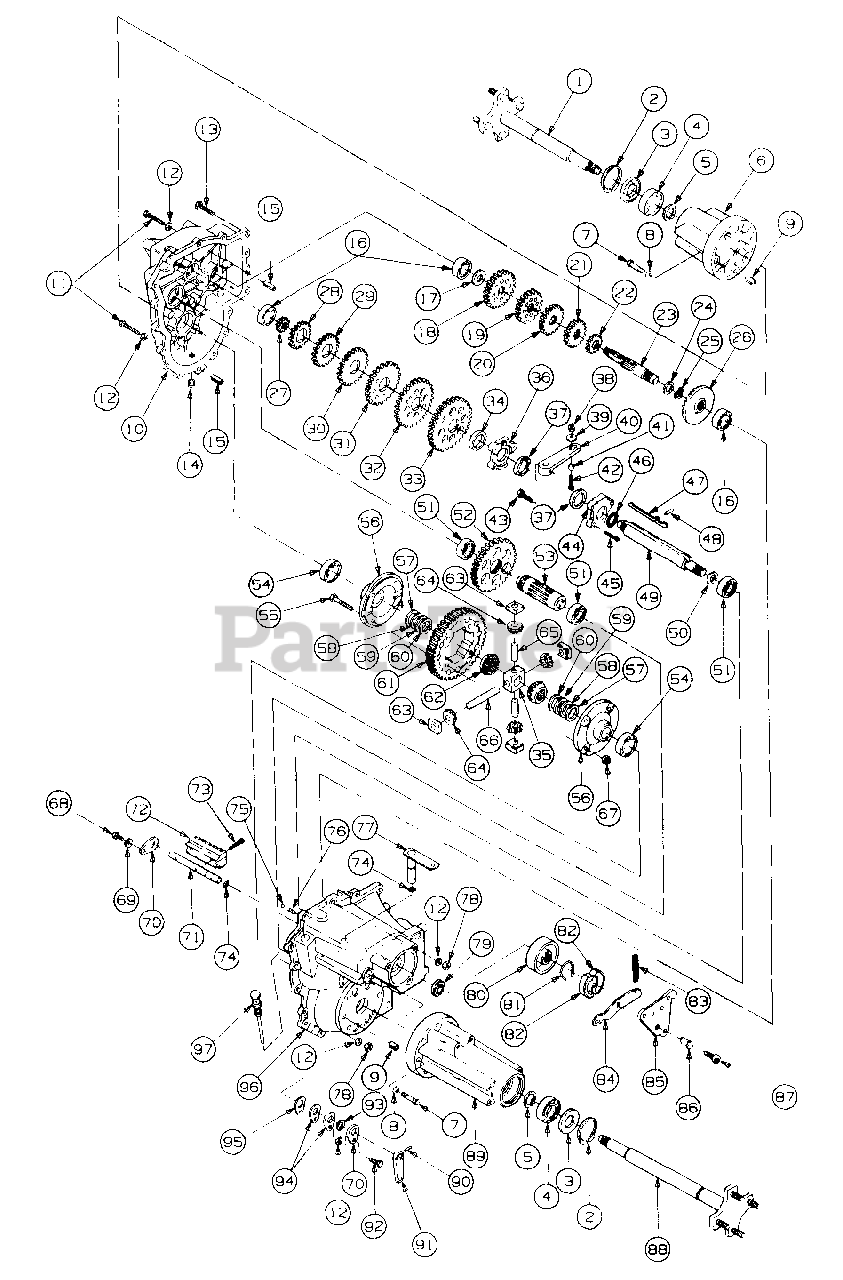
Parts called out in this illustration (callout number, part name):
1	Axle Assy, LH, 11.9" Lg
2	Ring, Inverted Retainer
3	Seal, Oil
4	Bearing
5	Ring, External Retainer
6	Housing, LH, Axle
7	Screw, Hex L-Wash Tapp 3/8-16 X 1.88 Lg
8	Washer, Bell
9	Bushing, Dowel
10	Housing, LH Differential
11	Screw, Hex Cap, 1/4-20 x 1.5 Lg
12	Washer, Flat, .25 x .62 x .052 Thk
13	Screw, Hex Wash TT-Tapp, 1/4-20 x 1.0 Lg
14	Plug, 1/2-14 NPTF
15	Pin, Slotted Spring, 7/16 x 1.0 Lg
16	Bearing, Ball
17	Washer, Flat, .68 x 1.25 x .060 Thk
18	Gear, 27T Drive, Sixth
19	Gear, 23T Drive, Fifth
20	Gear, 20T Drive, Fourth
21	Gear, 17T Drive, Third
22	Gear, 15T Drive, Second
23	Shaft, Drive w/First
24	Washer, Flat, .765 x 1.125 x .030 Thk
25	Washer, Wave, .79 x .99 x .012 Thk
26	Gear, 36T Bevel
27	Gear, 14T Reduction
28	Gear, 18T Shift, Sixth
29	Gear, 22T Shift, Fifth
30	Gear, 24T Shift, Fourth
31	Gear, 27T Shift, Third
32	Gear, 40T Shift, Second
33	Gear, 58T Shift, First
34	Spacer, Neutral
35	Block, Differential Pinion
36	Collar, LH, Shift
37	Spacer, Shift Key
38	Nut, Hex Center Lock, 5/16-18 GR5
39	Washer, Flat, .343 x .875 x .062 Thk
40	Arm, Key Shifter
41	Spacer, .316 ID x .440 OD x .263 Lg
42	Screw, Hex Cap, 5/16-18 x 1.0 Lg
43	Screw, Hex Cap, 5/16-18 x 1.25 Lg GR5
44	Collar, RH, Shift
45	Screw, Socket Hd Cap #10-32 x 1.25 Lg
46	Spring, Shift Key
47	Key, Shift
48	Pin, Dowel, 3/16 x 7/8 Lg
49	Shaft, Shift
50	Washer, Wave, .84 x 1.12 x .016 Thk
51	Bearing, Ball, .787 x 1.85 x .551 Thk
52	Gear, 44T Reduction
53	Shaft, 9T Output
54	Bearing, Ball
55	Screw, Hex Cap, 3/8-24 x 2.0 Lg
56	Cover, Differential
57	Washer, Flat, 1.0 x 1.56 x .010 Thk
58	Washer, Flat, 1.0 x 1.56 x .015 Thk
59	Washer, Flat, 1.0 x 1.56 x .020 Thk
60	Washer, Flat, 1.0 x 1.56 x .040 Thk
61	Gear, 60T Bull
62	Gear, 14T Differential Side
63	Block, Differential Thrust
64	Gear, 1OT Differential Pinion
65	Shaft, Cross
66	Shaft, Cross, .500 OD x 3.485 Lg
67	Nut, Hex Lock, 3/8-24
68	Screw, Hex Wash TT Tapp, 1/4-20 x .75 Lg
69	Washer, Bell, .265 x .75 x .062 Thk
70	Support, Interlock Shaft
71	Shaft, Interlock Shift
72	Interlock, Shift
73	Screw, Socket Hd Cap, 1/4-20 x 1.0 Lg
74	O-Ring, 1/2 ID x 5/8 OD
75	Ball, Detent, .250 Dia
76	Spring, Detent
77	Arm Assy, Shift
78	Nut, Hex Top Lock, 1/4-20
79	Seal, Shift Shaft
80	Drum, Brake
81	Spring, Brake
82	Shoe, Brake
83	Spring, Compression
84	Arm, Brake
85	Plate, Brake
86	Actuator, Brake Shoe
87	Screw, Low Hd Cap, 3/8-16 x .75 Lg
88	Axle Assy, RH, 15.6" Lg
89	Housing, RH, Axle
90	Pin, Spirol, 1/8 Dia x .812 Lg
91	Arm, Interlock Shift
92	Screw, Hex Wash TT Tapp, 1/4-20 x .75 Lg
93	Ring, Retainer
94	Shim, Interlock Shaft Support .030 Thk
95	Shim, Interlock Shaft Support .015 Thk
96	Housing, RH Differential
97	Dipstick, Oil
